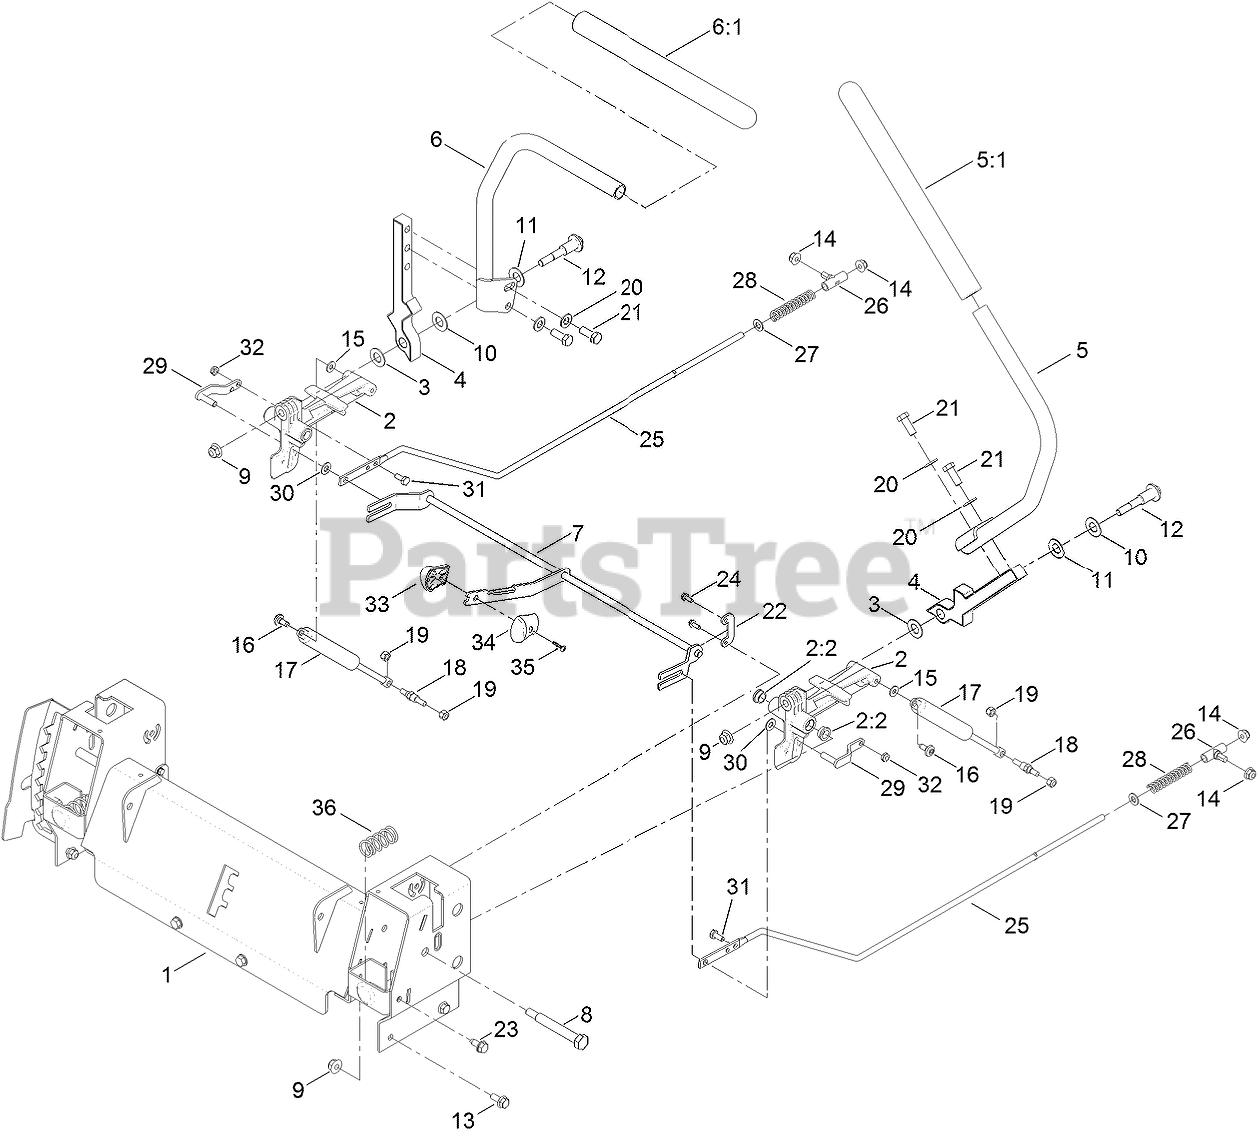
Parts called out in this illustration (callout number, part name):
1	CONTROL BOX ASM
2	ACTUATOR ARM ASM
2:2	BUSHING-FLANGE
3	WASHER-NYLON
4	LEVER-CONTROL
5	HANDLE-CONTROL, LH
6	HANDLE-CONTROL, RH
7	SPEED CONTROL ASM
8	BOLT-PIVOT
9	NUT-HF, NI
10	WASHER
11	WASHER-BELLEVILLE
12	BOLT-PIVOT
13	SCREW-HHF
14	NUT-HF, NI
15	WASHER
16	SCREW-SHOULDER
17	DAMPER
18	STUD-DAMPER
19	NUT-LOCK, NI
20	WASHER-FLAT
21	SCREW-HH
22	RETAINER
23	SCREW-HWHTF
24	SCREW-TAPTITE
25	ROD-HYDRO
26	MOUNT-ROD, HYDRO
27	WASHER-PLAIN
28	SPRING-RETURN, NEUTRAL
29	PIN-ROD, HYDRO
30	SPACER-NYLON
31	SCREW-HH
32	NUT-LOCK, NI
33	KNOB-RH
34	KNOB-LH
35	SCREW-PPH
36	SPRING-RETURN
